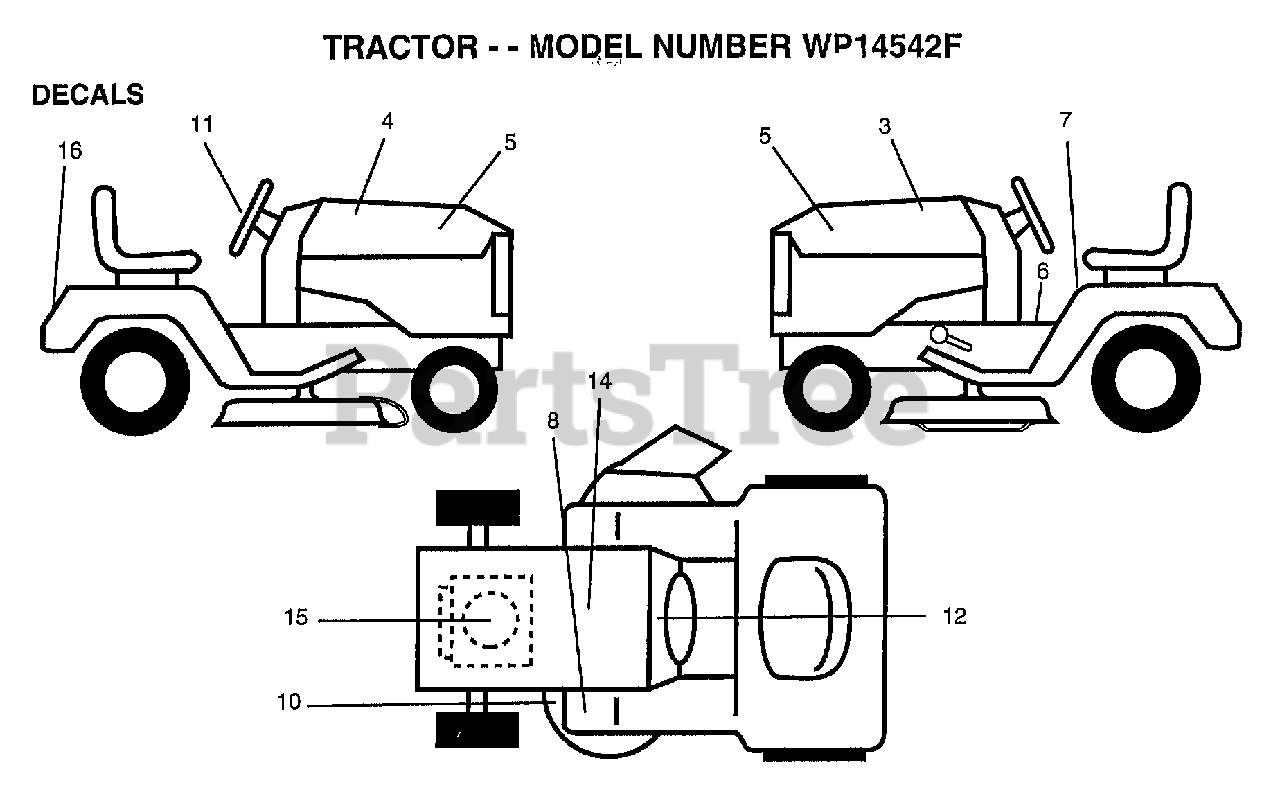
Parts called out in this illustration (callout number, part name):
3	DECAL.HOOD.LH
4	DECAL.HOOD.RH
5	DECAL.INS.HD.LT.
6	DECAL BRAK PARK
7	"DECAL DANGER,FEND"
10	"DECAL-SCHEM,BELT"
11	DECAL, INSERT
12	"DECAL-OPER,GEAR D"
14	DECAL.BATRY.3-3908
15	DECAL.ENGINE
16	DECAL, FENDER LOGO
